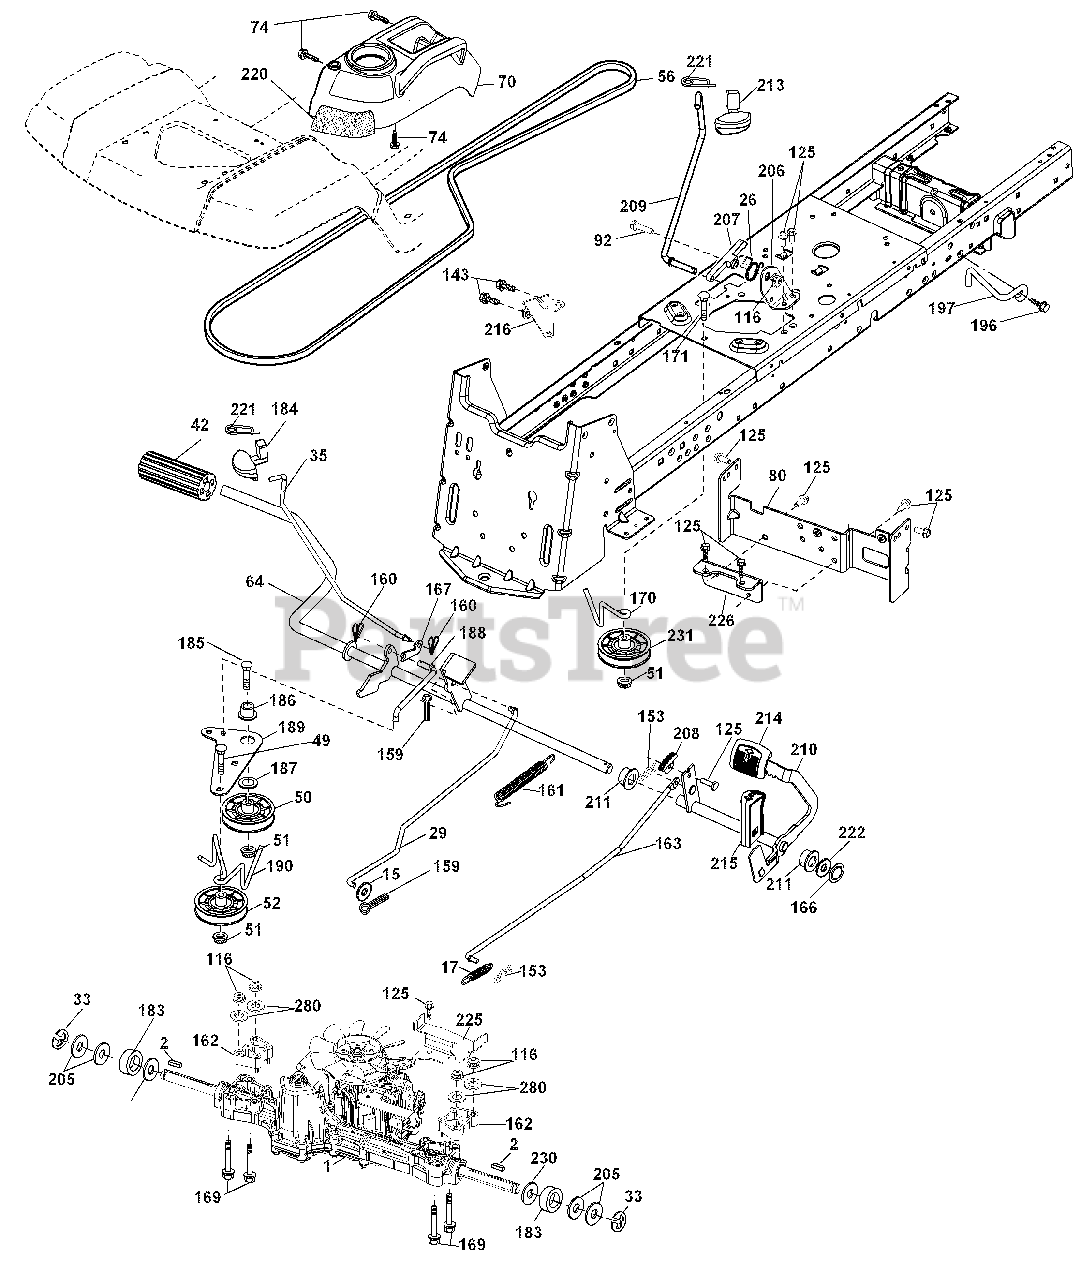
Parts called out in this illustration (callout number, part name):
1	Transaxle, TUFFTORQ K46
7	Hub Asm. Wheel
9	Bolt Hub Wheel
15	Washer 13/32 x 13/16 x 16 Ga.
17	Spring, Brake
26	Spring Return Cruise
29	Rod, Brake
35	Rod, Brake, Park
42	Cover, Foot Pedal
50	Pulley Idler Flat
51	Lock Nut 3/8-16
52	Idler V-Groove 910" Offset
56	V-Belt, Drive
64	Shaft Asm. Pedal Brake Control
70	Console Asm.
74	Screw 1/4 x 1/2
80	Strap Torque
92	Bolt Fin Hex 5/16-18 unc x 1.25
116	Nut Lock Hex Flange 5/16-18
125	Screw 5/16-18 x 3/4
143	Screw Thdrol 5/16-18 x 1/2
153	Retainer Spring
159	Pin Cotter 1/8 x 3/4
160	Retainer Clip
161	Spring, Return, Clutch
162	Spacer Transaxle
163	Rod Pedal Control
166	Nut Push .625
167	Latch Brake Parking
169	Bolt 5/16-18 x 4.5 Gr. 5
170	Keeper Belt Centerspan
171	Bolt 3/8 - 16 x 2-3/4 Gr. 5
183	Spacer Split
184	Handle Parking Brake
185	Bolt Rdhd Sqnk 3/8-16 x 2-1/2
186	Spacer Retainer
187	Washer
188	Link Clutch Ground Drive
189	Bellcrank Ground Drive
190	Keeper Bellcrank Ground Drive
196	Screw 3/8-16 x 1
197	Bracket Clutch Anti-Rotation
206	Bracket Mount Latch Cruise
207	Latch Control Cruise
208	Gear Sector Control Cruise
209	Rod Control Cruise
210	Rocker Asm. Pedal Control
211	Bearing Nylon
213	Knob Control Cruise
214	Pedal Forward
215	Pedal Reverse
216	Bracket Pulley Idler
220	Reflector RH
221	Retainer Spring Clip Handle
222	Washer 21/32 x 1-1/4 x 10 Ga.
225	Keeper Belt Trans.
226	Bracket Mount Touque
231	Idler V-Groove Pulley
280	Washer 11/32 x 5/8 x 12 Ga.
